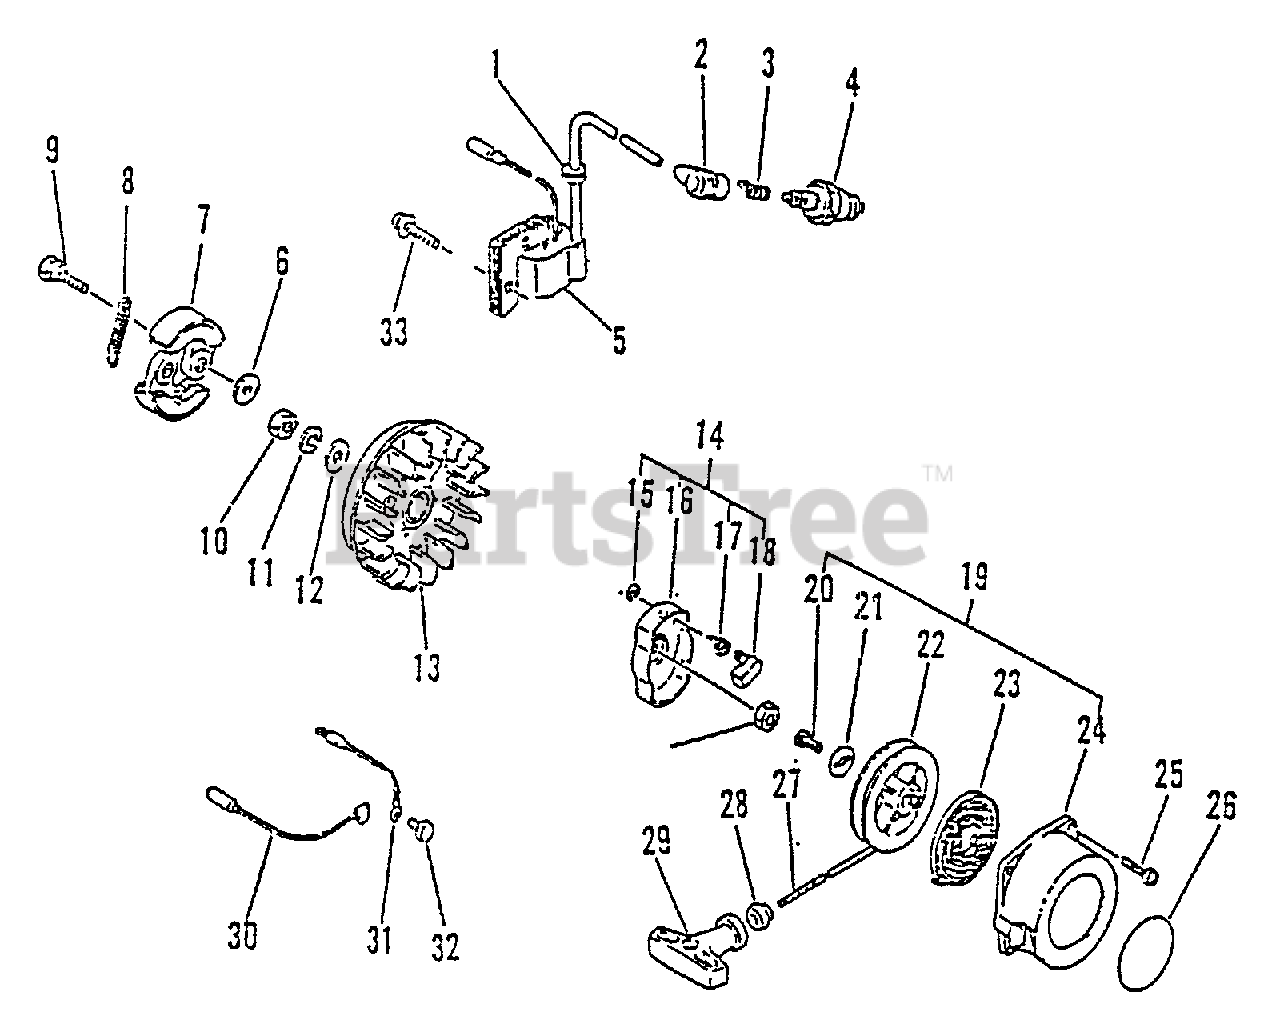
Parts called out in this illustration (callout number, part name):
2	CAP, SPARK PLUG
3	TERMINAL, SPARK PLUG CAP
4	SPARK PLUG -- BPM-7A
5	COIL, IGNITION
6	WASHER - 6
7	SHOE, CLUTCH
8	SPRING, CLUTCH
9	BOLT, CLUTCH
11	LOCKWASHER - 8
12	WASHER - 8
13	FLYWHEEL
14	STARTER PAWL ASSY
15	RING, RETAINING - 4
16	CATCHER, PAWL
17	SPRING, RETURN
18	PAWL, STARTER
19	STARTER ASSY - GRAY
21	WASHER
22	REEL, ROPE
23	SPRING, REWIND
24	CASE, STARTER
25	SCREW - 4X14
26	LABEL - ECHO
27	ROPE, STARTER - 3.5X850
28	GUIDE, ROPE
29	GRIP, STARTER
30	LEAD - GROUND
31	LEAD - GROUND
32	SCREW - 5X10
33	SCREW - 5X25
